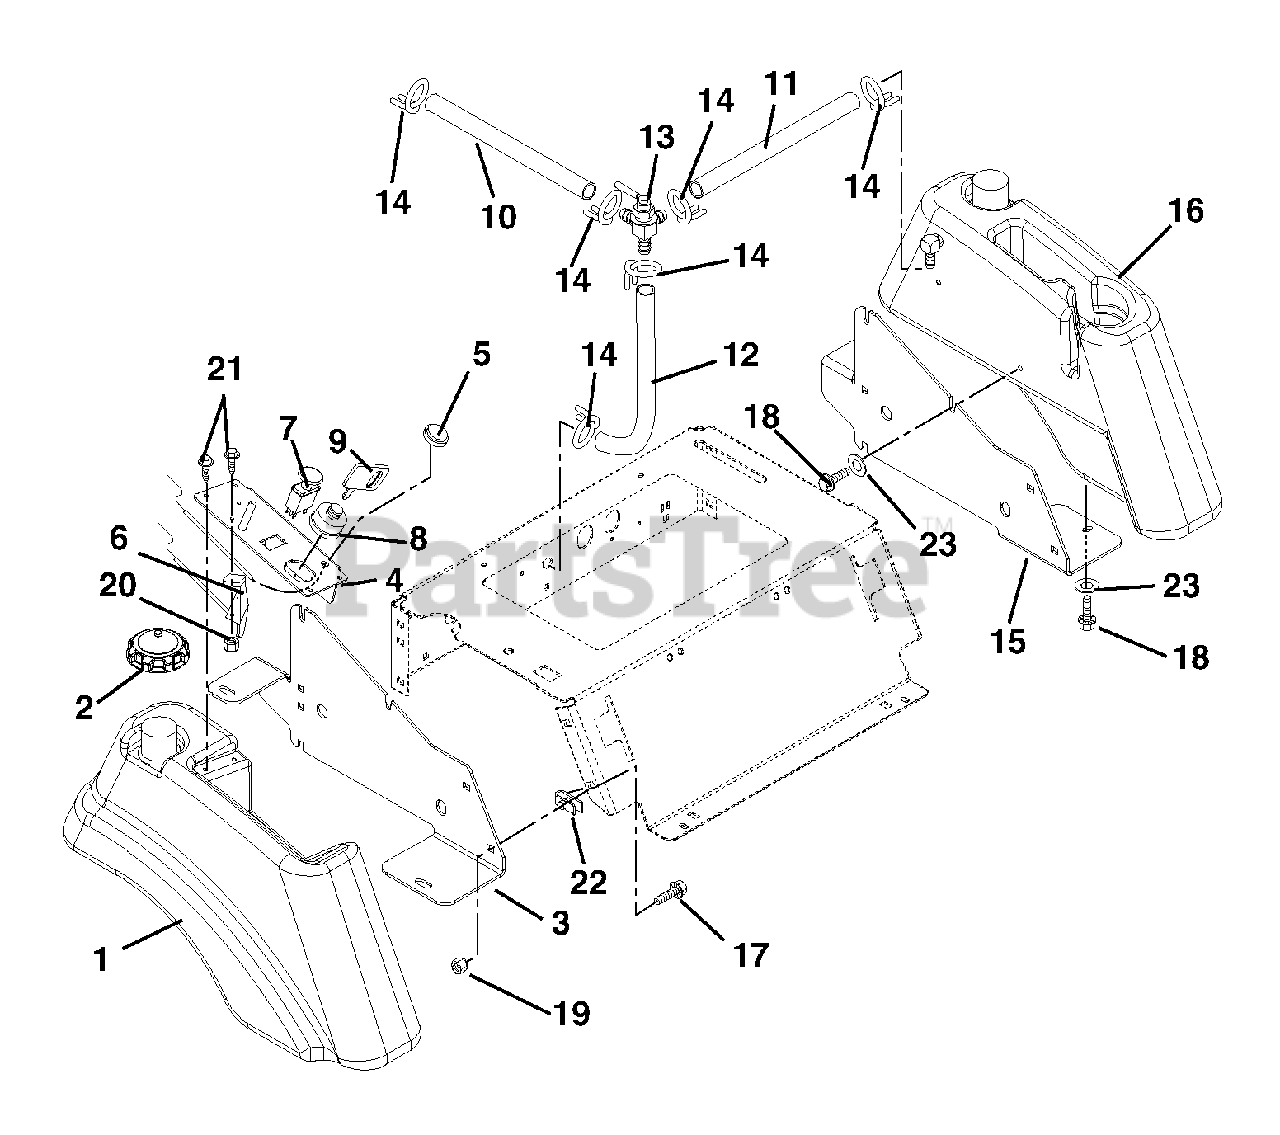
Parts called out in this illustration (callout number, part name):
1	Tank, Fuel - Right Hand
2	Fuel Cap
3	Seat Plate/Tank Support Right Hand
4	Bracket, Control
5	Hole Plug, Plastic .44 Hole
6	Throttle Cable
7	Switch, Clutch
8	Key Switch
9	Key with Cap
10	Gas Line, Bulk .25 I.D. x 38 Long
11	Gas Line, Bulk .25 I.D. x 26.5 Long
12	Gas Line, Bulk .25 I.D. x 14 Long
13	Valve, Fuel
14	Clamp, Hose Wire .490/.510 x .092
15	Seat Plate Left Hand
16	Tank, Fuel - Left Hand
17	Bolt, Round Head Square Neck .38-16 x 1.00 Grade 5
18	Bolt, Serrated Hex Flange Washer Head .312-18 x .75
19	Nut .38-16 Flange Nyloc
20	Nut, Locking Nylon 10-24 with Insert
21	Screw, Machine 10-24 x .50 Hex Washer Head
22	Retainer .38 Push-On
23	Washer, Flat Steel .328 x 1.00 x .094
NS	Fuel Fitting Bushing
